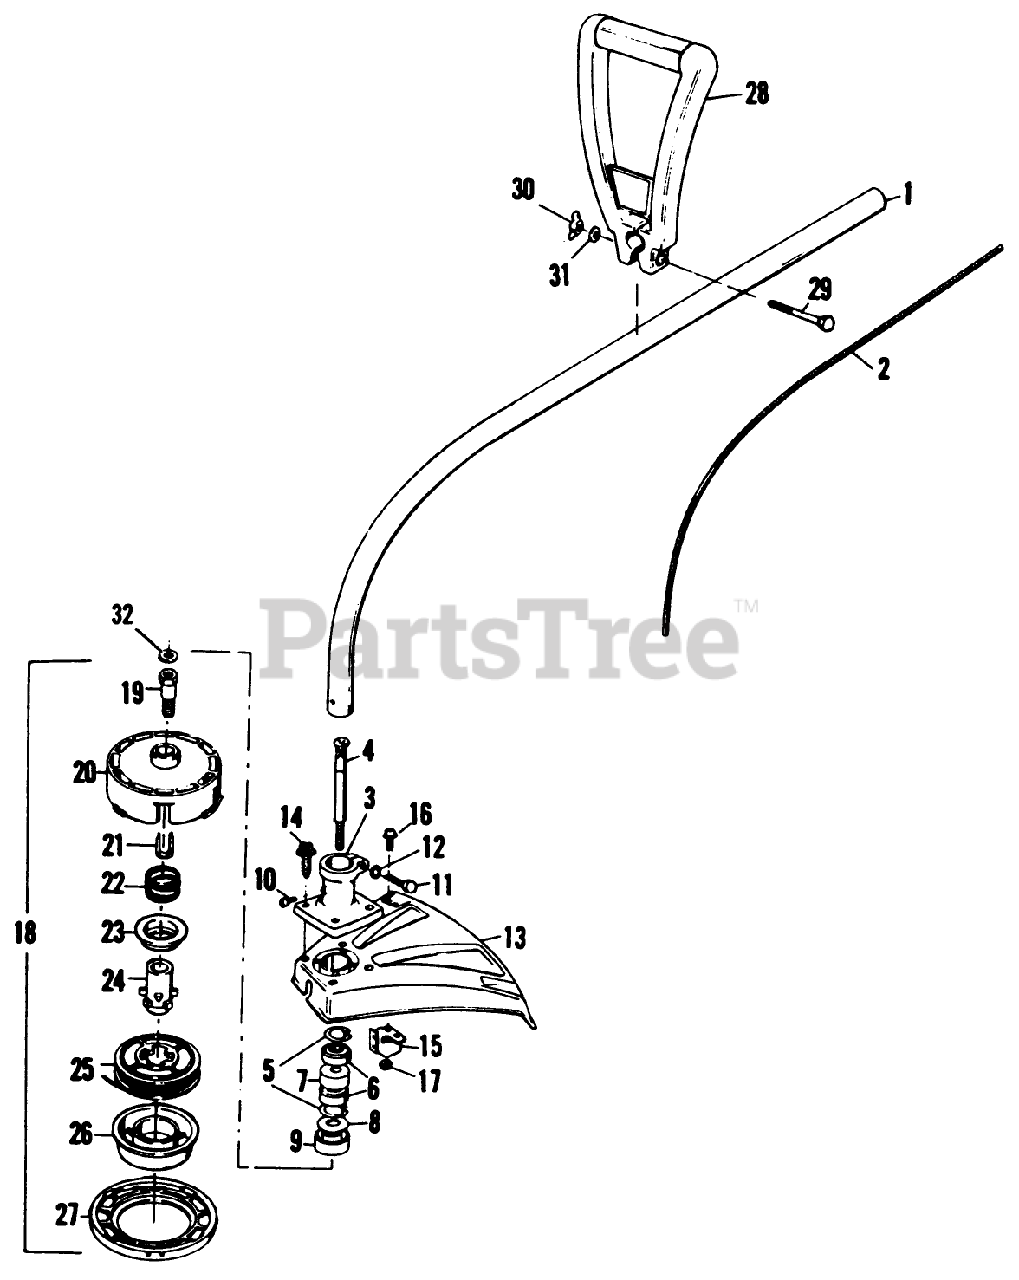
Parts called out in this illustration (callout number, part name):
1	Drive Shaft Housing 1700
1	Drive Shaft Housing 1600
2	Drive Shaft 1600
2	Drive Shaft 1700
3	Bearing Housing Assy
4	Shaft-Arbor
5	Retainer-Bearing
6	Bearing
7	Spacer-Bearing
8	Washer-Dust Cup
9	Dust Cup
10	Screw-Self-Tapping
11	Bolt-Pinch Clamp
12	Washer-1/4 Int. Tooth Lock
13	Splash Deflector 1700
13	Splash Deflector 1600
14	Screw-Shield to Bearing Hsg
15	Line Limiter
16	Screw-Line Limiter
17	Nut-Locking
18	Cutting Head Assy.
19	Bolt-Drive Adaptor
21	Line Saver
23	Adaptor-Spring
24	Drive Gear
25	Spool w/Line
26	Release Button
28	Assist Handle 1600
28	Assist Handle 1700
29	Special Washer
30	Wing Wing Nut-1/4-20
31	Washer-1/4 Flat
32	Grass Washer
